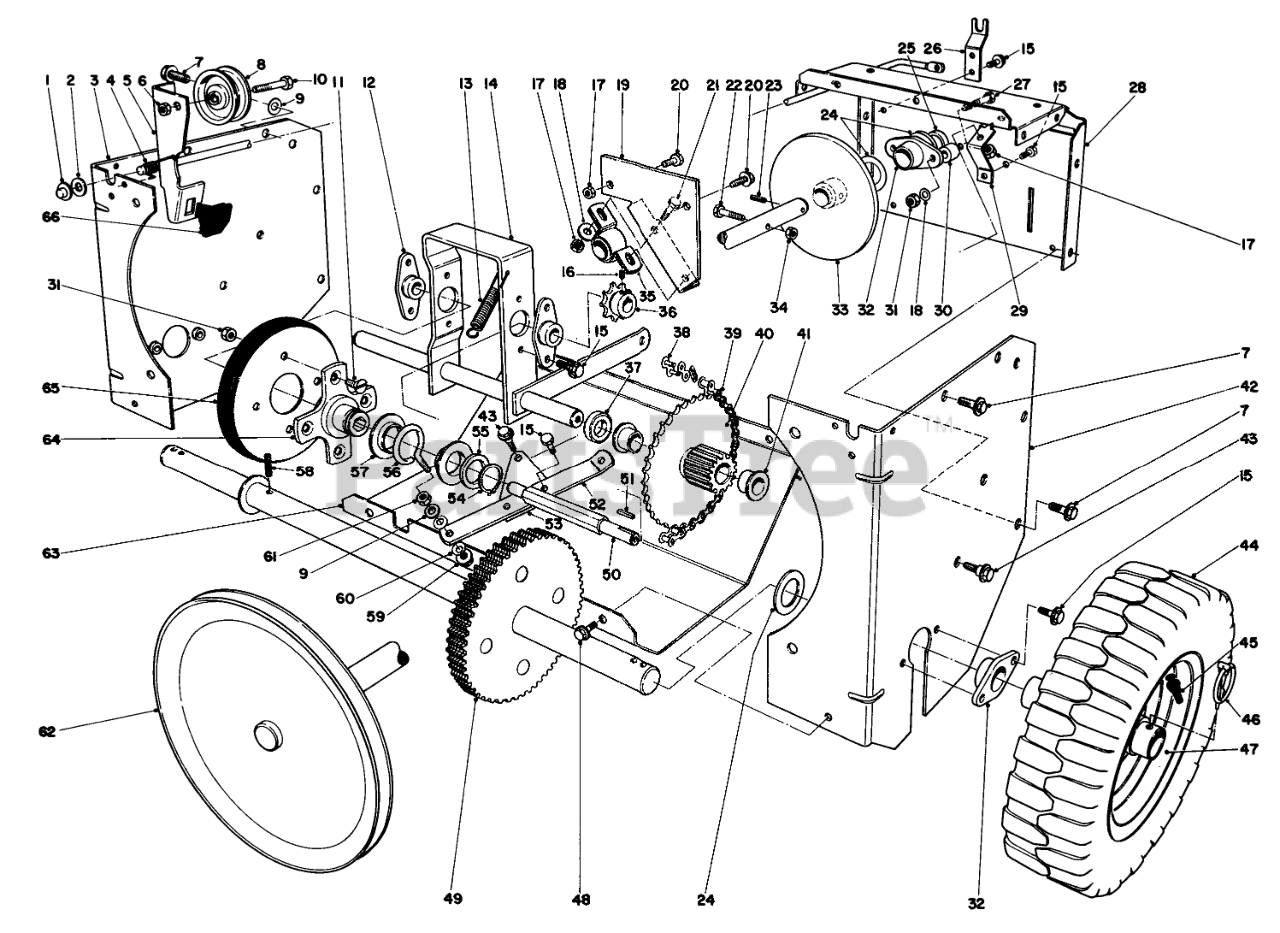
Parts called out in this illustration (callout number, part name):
1	PUSH NUT
2	WASHER-FLAT
3	RH TRACT SIDE PLT R
4	TORSION CLUTCH SPRING
5	Clutch Rod (Incl. Ref. #66)
6	NUT-HEX
7	SCREW-HHFTF
8	PULLEY-IDLER
9	WASHER-FLAT
10	SCREW-HH
11	5/16-18X5/8 FLT HD MS
12	BEARING-WHEEL, FRICTION
13	TENSION SPRING
14	PIVOT SHAFT WA B
15	SCREW-HWHTF
16	SCREW-HSH
17	NUT-LOCK, NI
18	WASHER-PLAIN
19	SHAFT SUPT BRKT B
20	SCREW-HH
21	SCREW-HH
22	SCREW-HH
23	PIN-ROLL, SLOTTED
24	WASHER
25	DRIVE SHAFT SPACER
26	CLUTCH ROD SUPPORT
27	SCREW-HH
28	CENTER FRAME R
29	PIVOT BRACKET
30	BRG STANDOFF
31	Nut
32	AXLE BEARING
33	FRICTION PLT WA
34	NUT-LOCK, CONE
35	PILLOW BLOCK BRG
36	SPROCKET
37	COSHAFT SPACER
38	LINK-CONNECTING
39	ROLLER-CHAIN
40	Gear & Bushing (Incl. Ref. #41)
41	BUSHING
42	LH TRACT SIDE PLT R
43	SHOULDER SCREW
44	Tire
45	STEM-VALVE
46	PIN-LYNCH
47	Wheel
48	SCREW-HWH
49	AXLE & GEAR WA
50	FRICTION WHL SHAFT
52	SHIFT LINKAGE
53	PIVOT PLATE
54	RING-RETAINING
55	WASHER-THRUST
56	SLIDER RING COLLAR
57	SLIDER RING
58	PIN-ROLL, SLOTTED
59	NUT-LOCK, FLANGE
60	WASHER-SPRING
61	Nut
62	PULLEY/SHFT WA
63	LOWER SHIELD R
64	TRACTION DISC HUB
65	FRICTION WHEEL
66	Brake Pad
